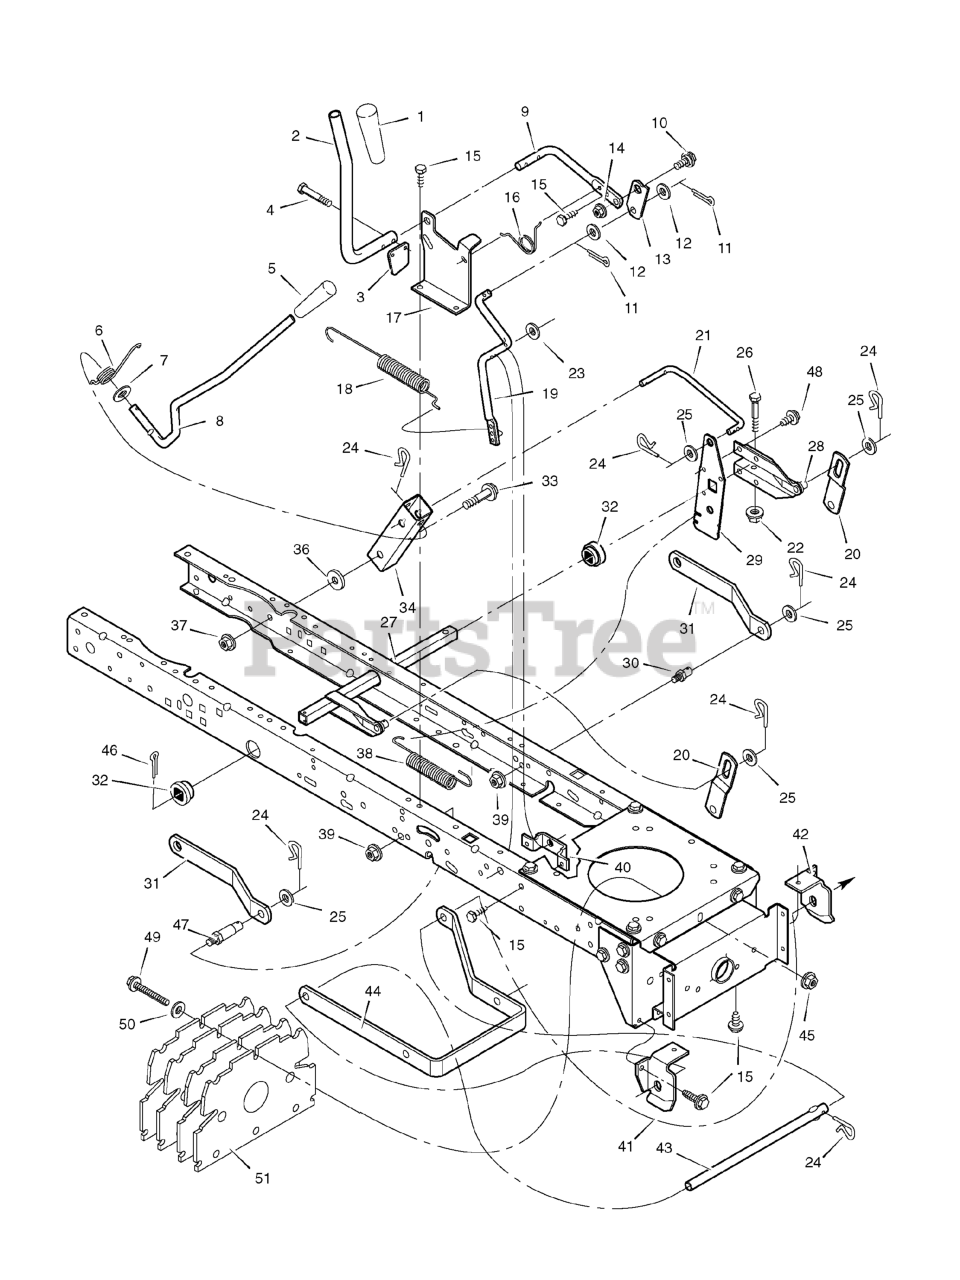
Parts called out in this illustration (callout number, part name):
1	Grip
2	Handle, PTO
3	Pad, Switch
4	Screw, Hex
5	Grip
8	Handle, Lift
9	Lever, PTO
10	Bolt, Shoulder
11	Pin, Cotter
13	Link, PTO
14	Nut, Flange
17	Bracket, PTO
19	Crank, PTO
20	Link, Lift
21	Link, Lift Handle
22	Nut, Flange
24	Pin, Hair
26	Bolt, Hex
27	Arm Assembly, Right Lift
28	Arm, Right Lift
29	Plate, Lift Arm
30	Pin
31	Bracket, Rear Suspension
32	Bushing, Lift Tube
33	Bolt, Shoulder
34	Bracket, Pivot
37	Nut, Flange
39	Nut, Flange
40	Bracket, PTO
41	Hanger, Right Deck
42	Hanger, Left Deck
43	Rod, Hanger
44	Hanger, Front
45	Nut, Flange
46	Pin, Cotter
47	Pin, Threaded Shoulder
49	Bolt, Hex
51	Plate, Weight (4 Required)
